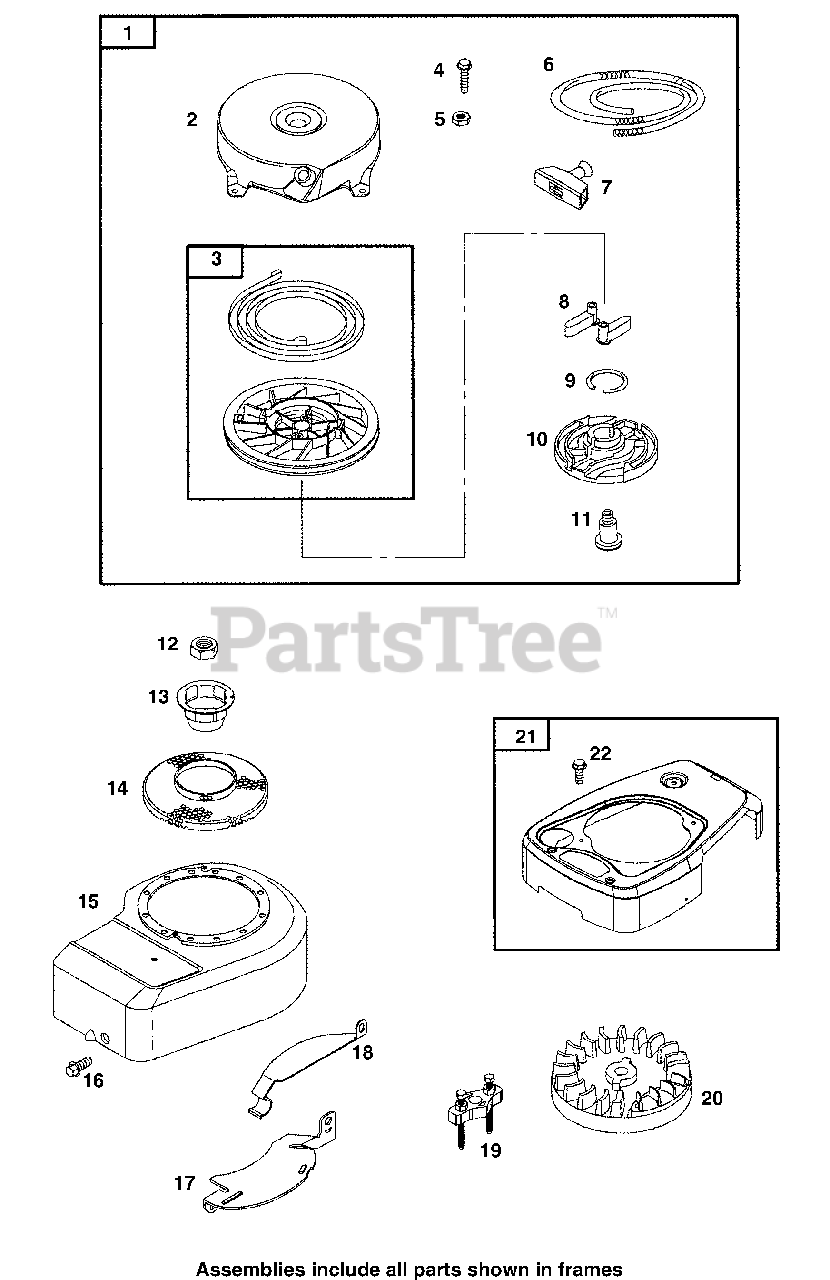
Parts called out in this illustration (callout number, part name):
1	Starter-Rewind
2	Housing-Rewind Starter
3	Assembly-Pulley Spring
4	Hex Screw
5	Hex Nut
6	Starter Rope
7	Starter Rope Grip
8	Pawl-Rachet
9	Spring-Friction
10	Plate-Pawl Friction
11	Shoulder Screw
12	Flywheel Nut
13	Flywheel Cup
14	Rotating Screen
15	Blower Housing
16	Hex Screw
17	Flywheel Guard
19	Flywheel Puller
21	Blower Housing Cover
22	Hex Screw
